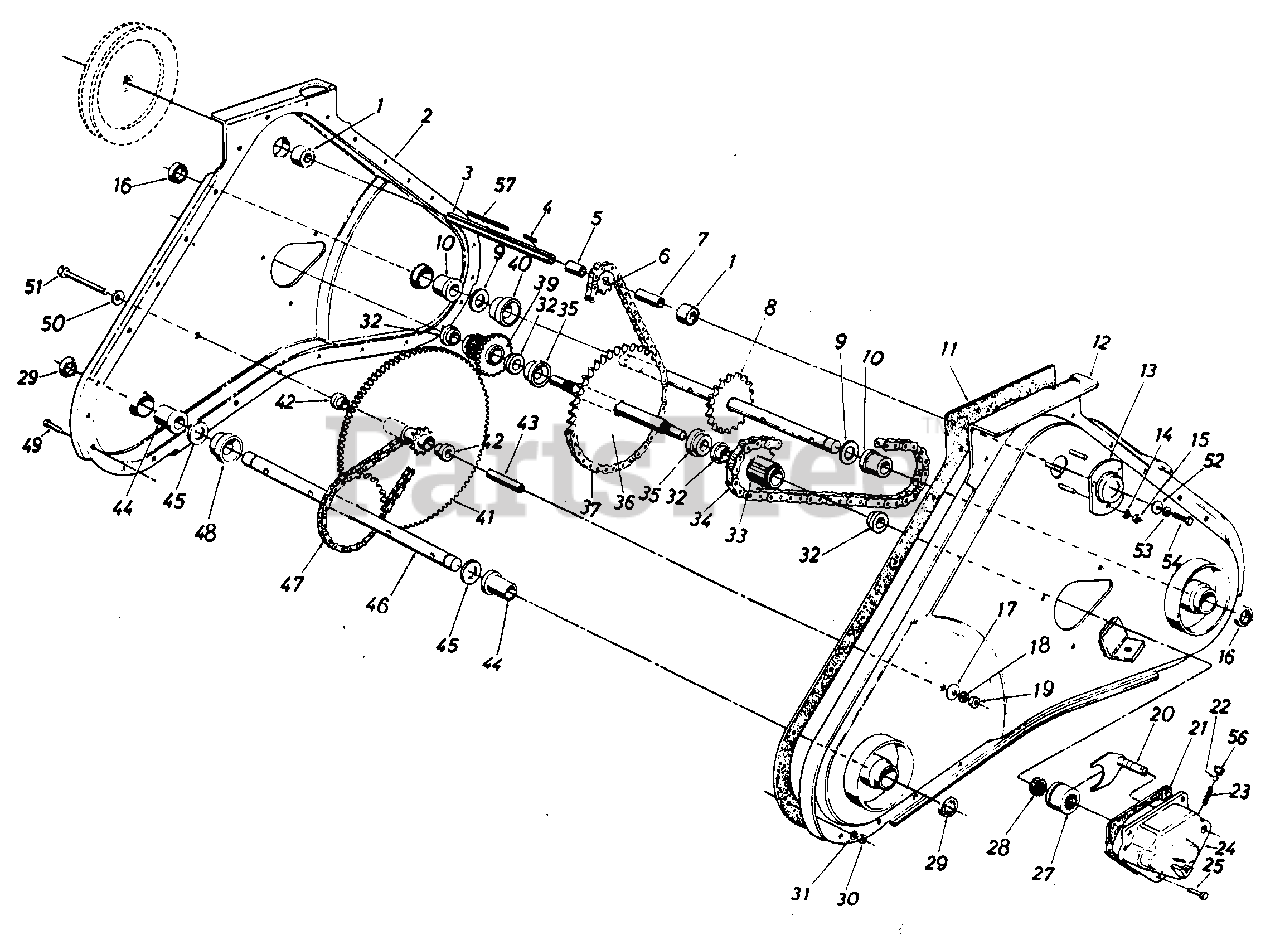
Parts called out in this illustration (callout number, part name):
1	Ball Bearing .62" I.D. x 1.38" O.D. x .44
2	Chain Case R.H. Half
3	Input Shaft .62" Dia.
4	Sq. Key 3/16" x 3/16" x .75"
5	Spacer .637" I.D. x .781" O.D. x .85" Lg.
6	Sprocket 9 Tooth x .62" Shaft
7	Spacer .637" I.D. x .781" O.D. x 1.44" Lg.
8	Tine Shaft Ass'y.
9	Fl-Wash. 1.28" I.D. x 1.62" O.D.
10	Flange Bearing 1.25" I.D.
11	Gasket-Housing
12	Chain Case L.H. Half
13	Bearing Housing 1-3/8" O.D.
14	L-Wash. 1/4" I.D.
15	Hex Nut 1/4-28 Thd.
16	Seal 1.25" I.D.
17	Belleville Wash.
18	L-Wash. 3/8" I.D.
19	Hex Cent. L-Nut 3/8-24 Thd.
20	Shift Yoke Ass'y.-L. H.
21	Gasket-Shift Housing
22	Ball Detent .250 Dia.
23	Compression Spring
24	Shift Housing-L.H.
25	Hex Tap-Tite 5/16-18 x .75" Lg.
27	Clutch Dog
28	Clutch Dog Driver
29	Seal 1.0" I.D. x 1.38" O.D.
30	Hex Nut 1/4-28 Thd.
31	L-Wash. 1/4" I.D.
32	Flange Brg. 1.00" I.D.
33	Sprocket Brg. Sleeve Ass'y.
34	#50 Chain-5/8" Pitch x 50 Links-Endless
35	Stepped Spacer 1.0" I.D. x 1.75" O.D.
36	Clutch Shaft Ass'y.
37	#420 Chain 1/2" Pitch x 58 Links-Endless
39	Gear Bearing-Sleeve Ass'y.
40	Spacer 1.25" I.D. x 2.0 O.D. x .68" Lg.
41	Sprocket and Gear Ass'y.
42	Flange Brg. .628" I.D. x .753" O.D.
43	Hub Sleeve .38" I.D. x .625" O.D.
44	Flange Brg. 1.00" I.D. x 1.188" O.D.
45	Fl-Wash. 1.0" I.D. x 1.62" O.D.
46	Axle Shaft Ass'y.
47	#420 Chain 1/2" Pitch 46 Links-Endless
48	Spacer 1.0" I.D. x 2.0" O.D.
49	Hex Bolt 1/4-28 x .62" Lg.
50	Belleville Wash.
51	Hex Bolt 3/8-24 x 2.75" Lg.
52	Fl-Wash. 5/16" I.D.
53	L-Wash. 5/16" I.D.
54	Hex L-Bolt 5/16-24 x .75" Lg.
56	Cap Plug .250" Dia.
57	Sq. Key 3/16" x 2.0" Lg.
